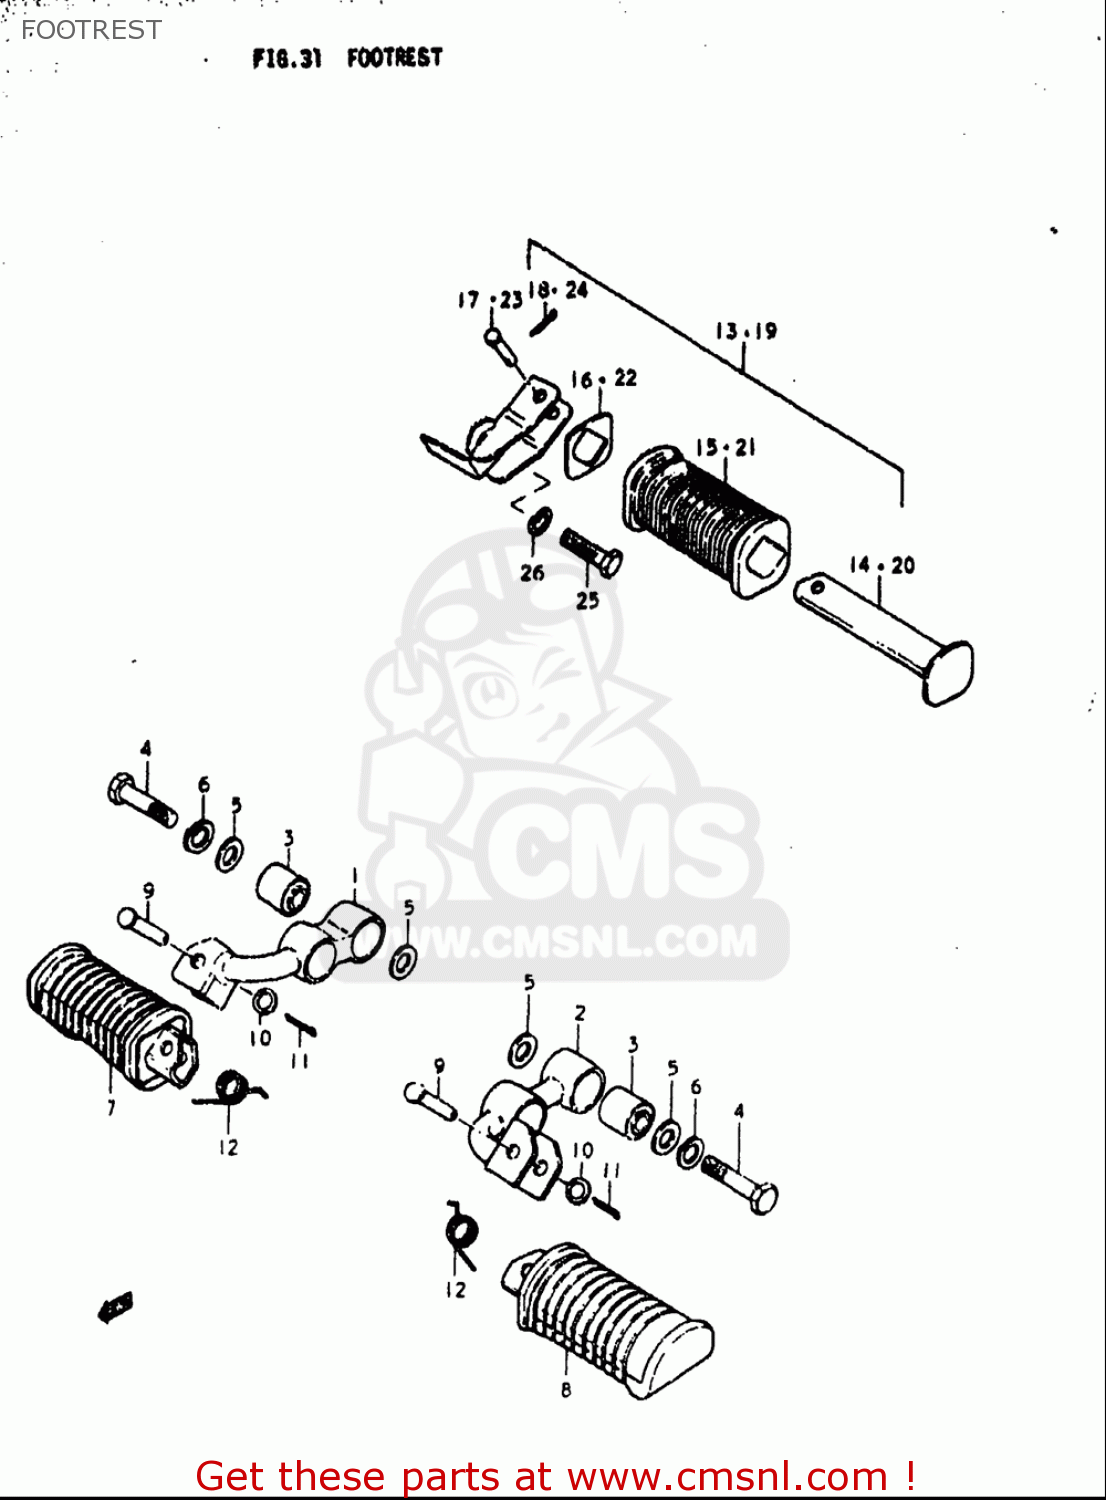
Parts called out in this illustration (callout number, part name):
2	BAR,FRONT FOOTREST,LEFT
3	BUSH
4	BOLT(10X38)
5	WASHER(10.5X20X2.3)
6	WASHER,LOCK
7	RUBBER,PILLION FOOTREST,R
8	RUBBER,PILLION FOOTREST,L
9	PIN
10	WASHER
11	PIN
12	SPRING
15	RUBBER,PILLION FOOTREST
16	WASHER,PILLION FOOTREST RUBBER
17	PIN
18	PIN
21	RUBBER,PILLION FOOTREST
22	WASHER,PILLION FOOTREST RUBBER
23	PIN
24	PIN
25	BOLT
26	WASHER,LOCK
